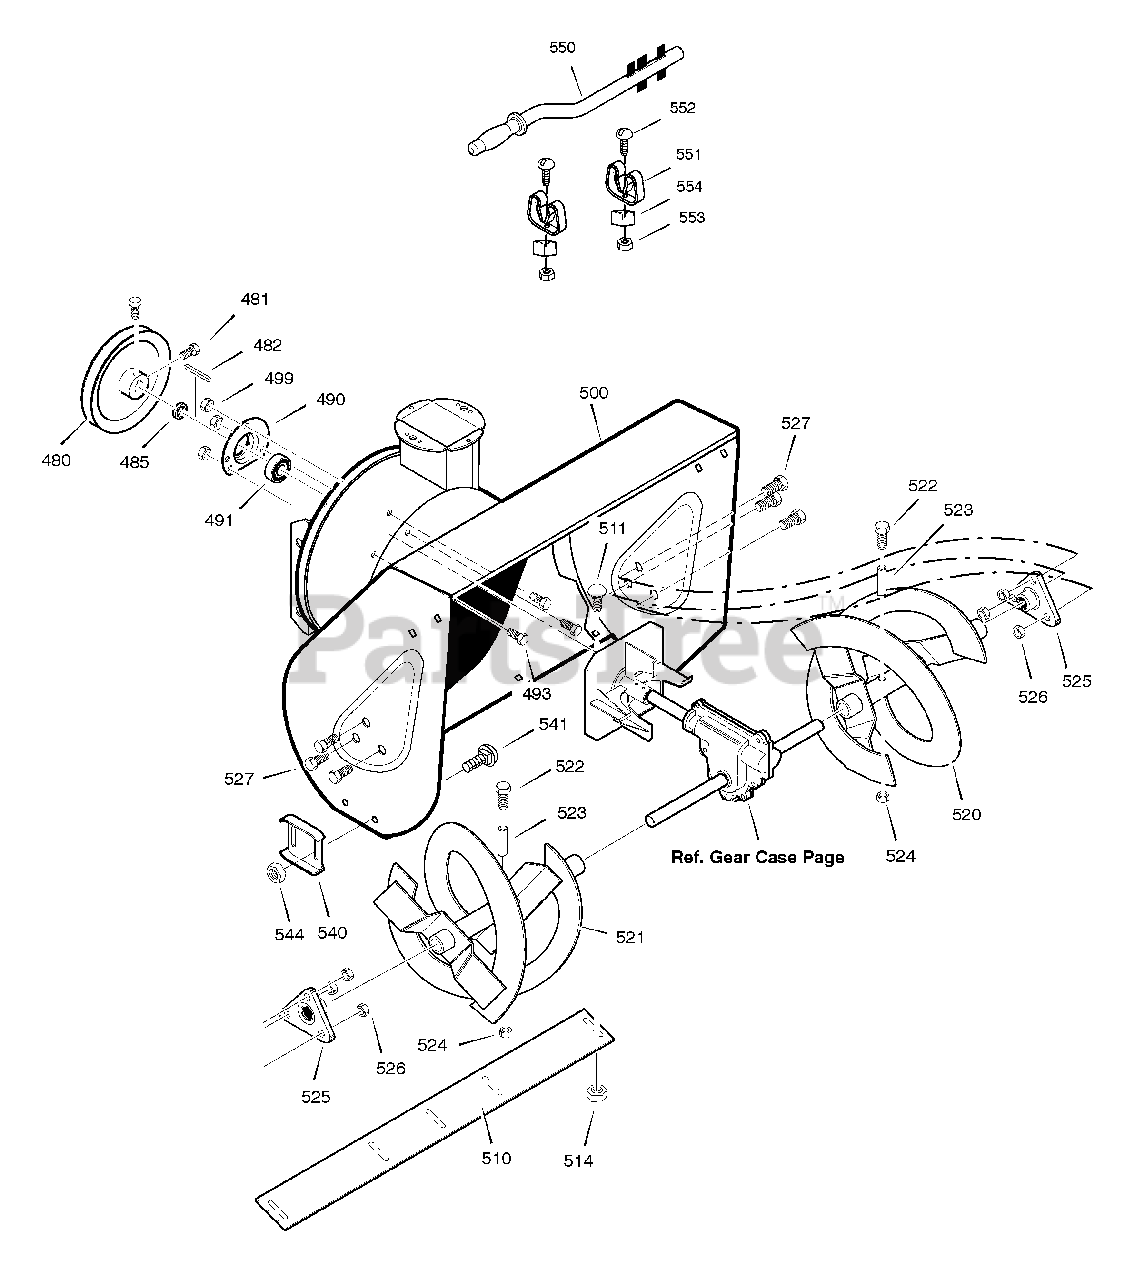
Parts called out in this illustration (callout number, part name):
480	PULLEY, 4L 6.12X .67
481	SCREW, 5/16-18 x 0.63
482	KEY, SQUARE 3/16 X 3/4
485	SPACER, FRICTION PULLEY
490	RETAINER, BALL BRNG
491	BEARING, BALL
493	BOLT, HEX 5/16-18X .50
499	NUT, 5/16-18 HEXWDFLLK
500	HOUSING, ASSY
510	BLADE, SCRAPER
511	BOLT, 1/4-20X.62
514	NUT, 1/4-20
520	AUGER, ASSY, LH
521	AUGER, ASSY, RH
522	SCREW, 1/4-20X1.75
523	SPACER, SLEEVE
524	NUT, 1/4-20
525	BEARING,FLANGE
526	NUT, 5/16-18
527	SCREW, 5/16-18 x 0.75
540	SKID, HEIGHT ADJUST
541	BOLT, 5/16-18 X .75
544	NUT, 5/16-18
550	BRUSH, CLEANOUT
551	CLIP, RETAINER
552	SCREW
553	NUT
554	BLOCK
